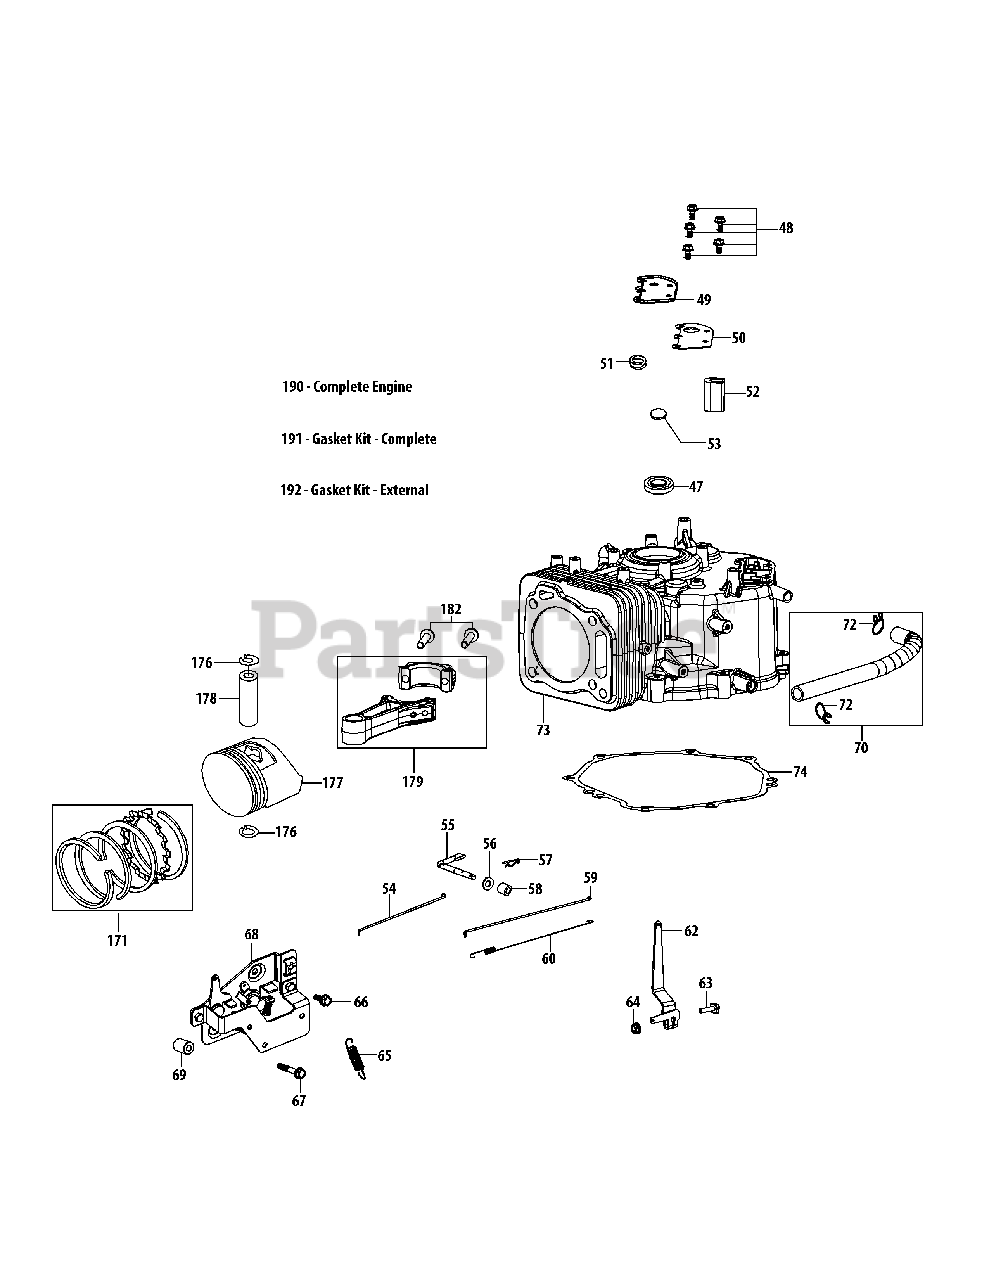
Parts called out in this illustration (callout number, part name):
47	Upper Crankshaft Seal
48	Bolt M6x14
49	Breather Cover Plate
50	Breather Gasket
51	Umbrella Valve
52	Mesh Screen
53	Umbrella Valve Set
54	Choke Linkage
55	Governor Arm Shaft/Improved
56	Governor Washer
57	Governor Cotter Pin
58	GOVERNOR SEAL
59	Throttle Linkage
60	Throttle Linkage Spring
62	Governor Arm
63	Governor Arm Bolt
64	Governor Arm Nut M6
65	Governor Spring
66	Bolt M6x18
67	Bolt M6x38
68	Component Bracket/Separate
69	Component Bracket Spacer
70	Breather Hose Assembly
72	Breather Hose Clamp
73	Crankcase
73	Short Block Assembly
74	Crankcase Cover Gasket
171	Piston Ring Set
176	Piston Pin Snap Ring
177	Piston
178	Piston Pin
179	Connecting Rod Assembly
182	Connecting Rod Bolt
190	Complete Engine
191	Gasket Kit - Complete
192	Gasket Kit - External
